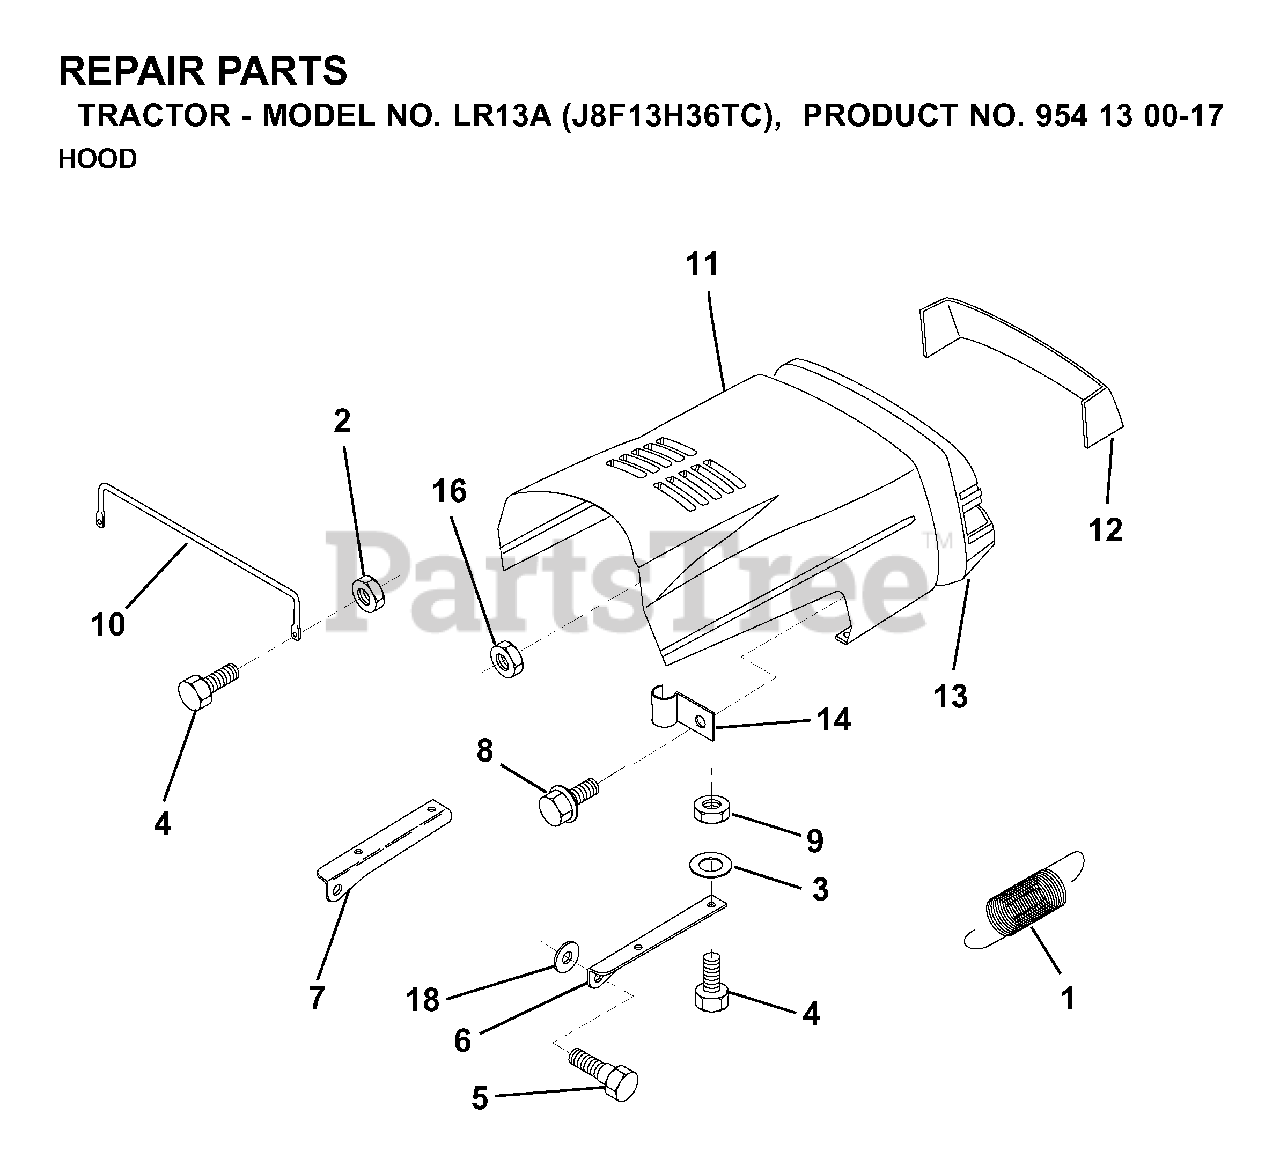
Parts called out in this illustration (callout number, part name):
1	EXT SPRING
2	NUT
4	BOLT
6	BRKT HOOD RH
7	BRKT HOOD LH
8	SCREW
9	LOCKNUT
10	BRACE,HOOD
18	WASHER
